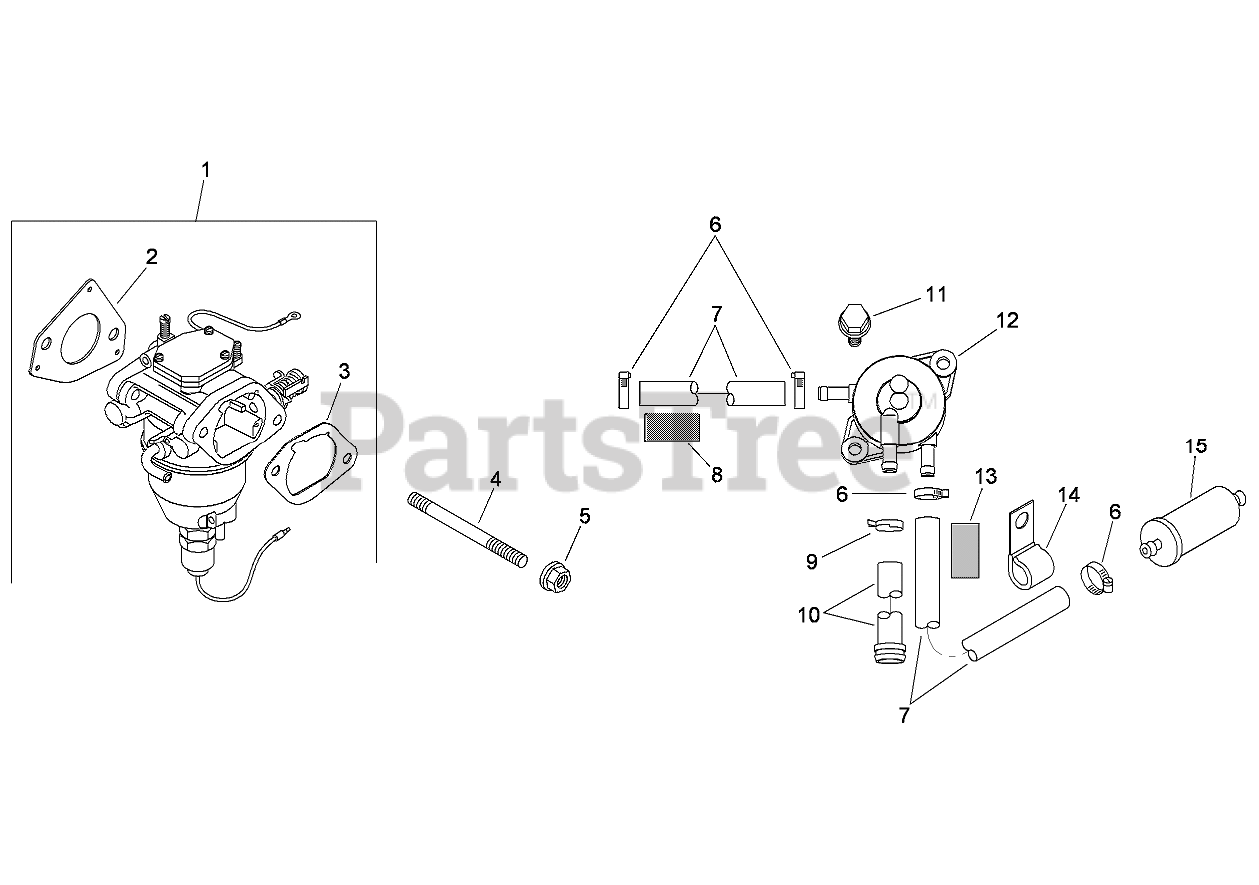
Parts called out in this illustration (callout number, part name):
1	CARBURETOR W/GASKETS KIT (INCLUDES 2, 3)
2	GASKET-CARBURETOR
3	GASKET-BASE, AIR CLEANER
4	STUD (M6X1.0X106)
5	NUT-FLANGE (M6X1.0)
6	CLAMP-HOSE, SPRING (1/2)
7	LINE-FUEL (24.0 CUT TO LENGTH)
8	SLEEVE-ABRASION, ANTI
9	CLAMP-HOSE
10	FUEL PUMP HOSE KIT (W/CLAMP) (INCLUDES 9)
11	SCREW-TAP (M6X1.7X18)
12	PUMP-FUEL
13	SLEEVE-ABRASION, ANTI
14	Filter-Fuel
15	CLIP-CABLE
